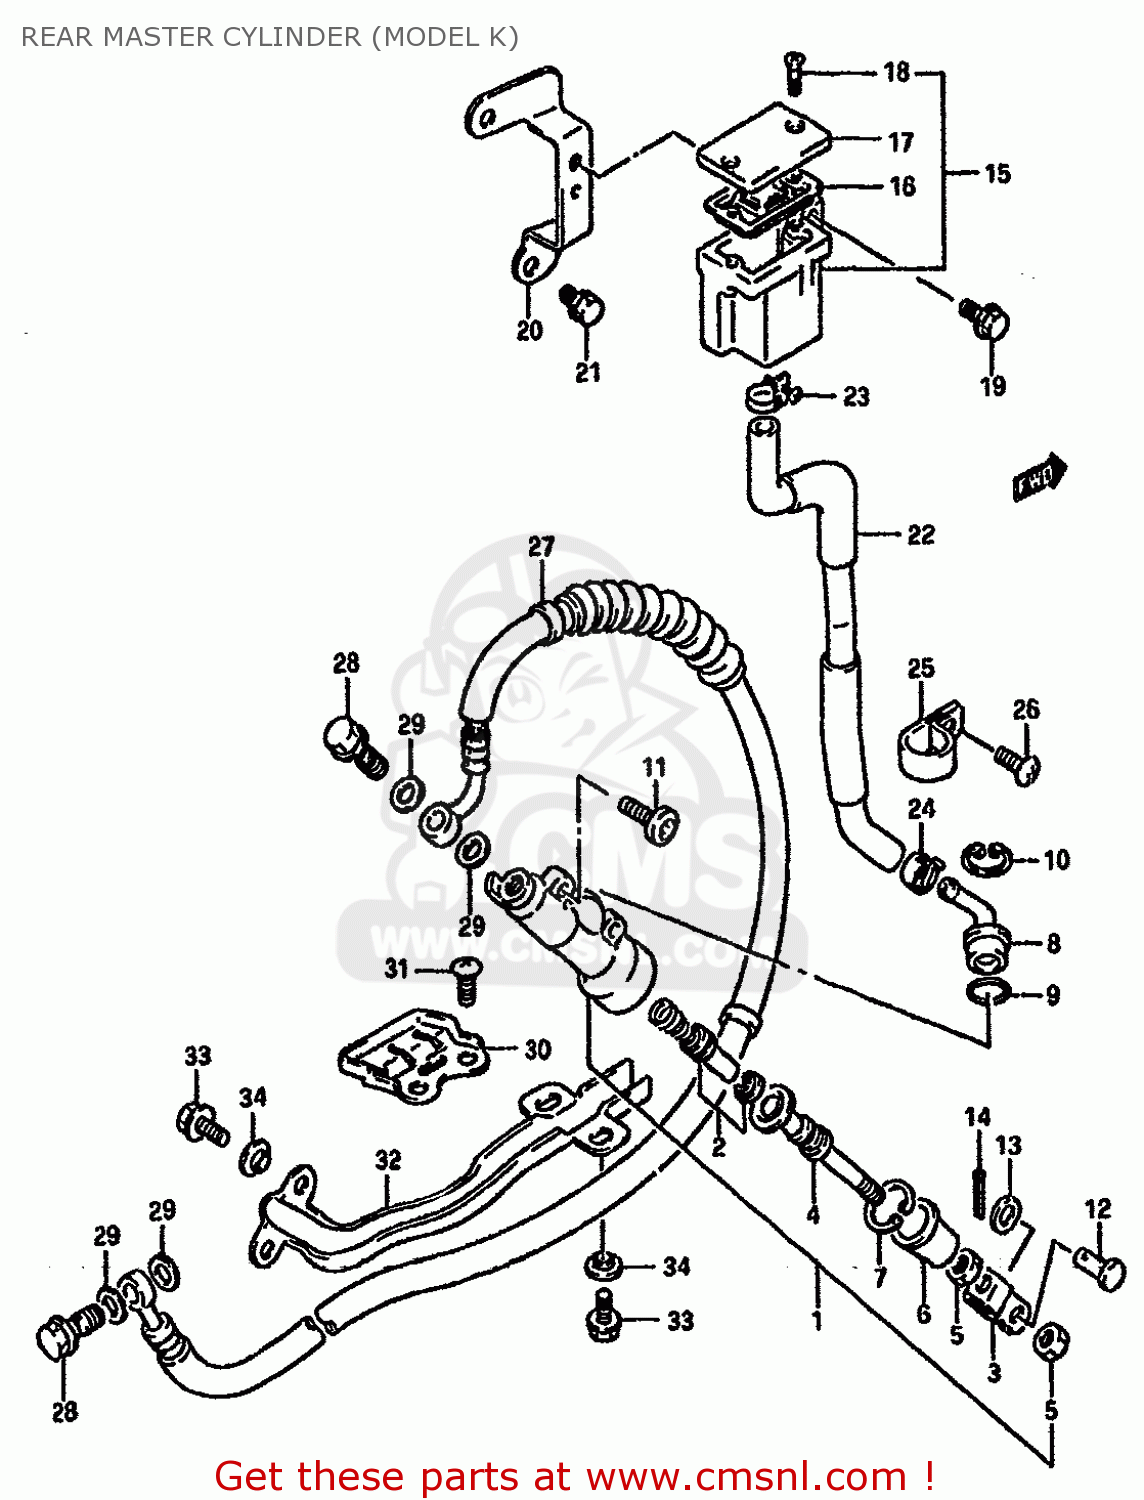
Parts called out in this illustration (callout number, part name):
1	CYLINDER ASSY,REAR MASTER
2	PISTON/CUP SET
3	YOKE
4	ROD,PUSH
5	NUT
6	BOOT
7	CIRCLIP
8	CONNECTOR
9	O RING
10	CIRCLIP
11	BOLT(6X18)
12	PIN(8X20)
13	WASHER(8.5X13X1.6)
14	PIN
15	TANK ASSEMBLY,RESERVOIR
16	DIAPHRAGM
17	CAP
18	SCREW
19	BOLT 6X16
20	PLATE,RESERVOIR TANK
21	BOLT(6X8)
22	HOSE,RESERVOIR TANK
23	CLAMP
24	CLAMP
25	CLAMP,HOSE GUIDE
26	SCREW
27	HOSE,REAR BRAKE
28	BOLT UNION
29	WASHER(10X15X1.5)
30	GUIDE,BRAKE HOSE (SILVER)
31	SCREW
32	PROTECTOR, BRAKE HOSE
33	BOLT
34	WASHER
